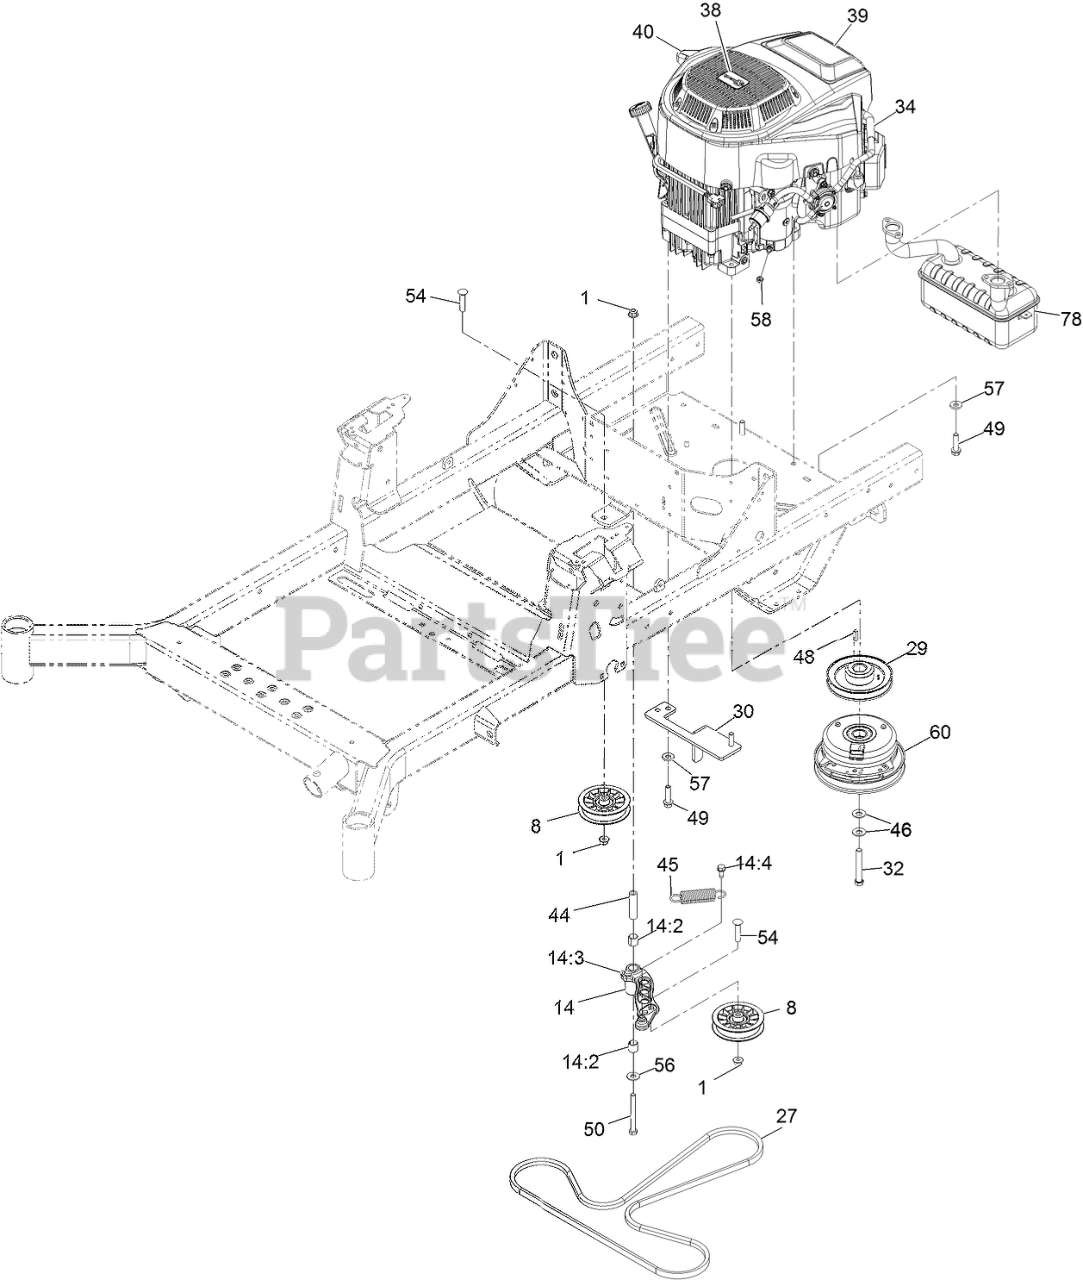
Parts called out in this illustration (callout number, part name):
1	NUT-HF, NI
8	PULLEY-FLAT IDLER
14	IDLER ARM ASM
14:2	SLEEVE-BEARING
14:3	FITTING-GREASE, 90 DEG
14:4	SCREW-THD ROLL, HWH
27	BELT-V
29	SHEAVE-ENGINE
30	ANCHOR-CLUTCH
32	SCREW-HH W/LOCTITE
34	ENGINE-2P77F
40	DECAL-DRAIN, OIL
44	BUSHING-PIVOT, IDLER
45	SPRING-EXTENSION
46	WASHER-SPRING
49	SCREW-HWH
50	SCREW-HH
54	SCREW-CARR
56	WASHER-FLAT
57	WASHER-BELLEVILLE
60	CLUTCH - 1.00 HD
78	MUFFLER
